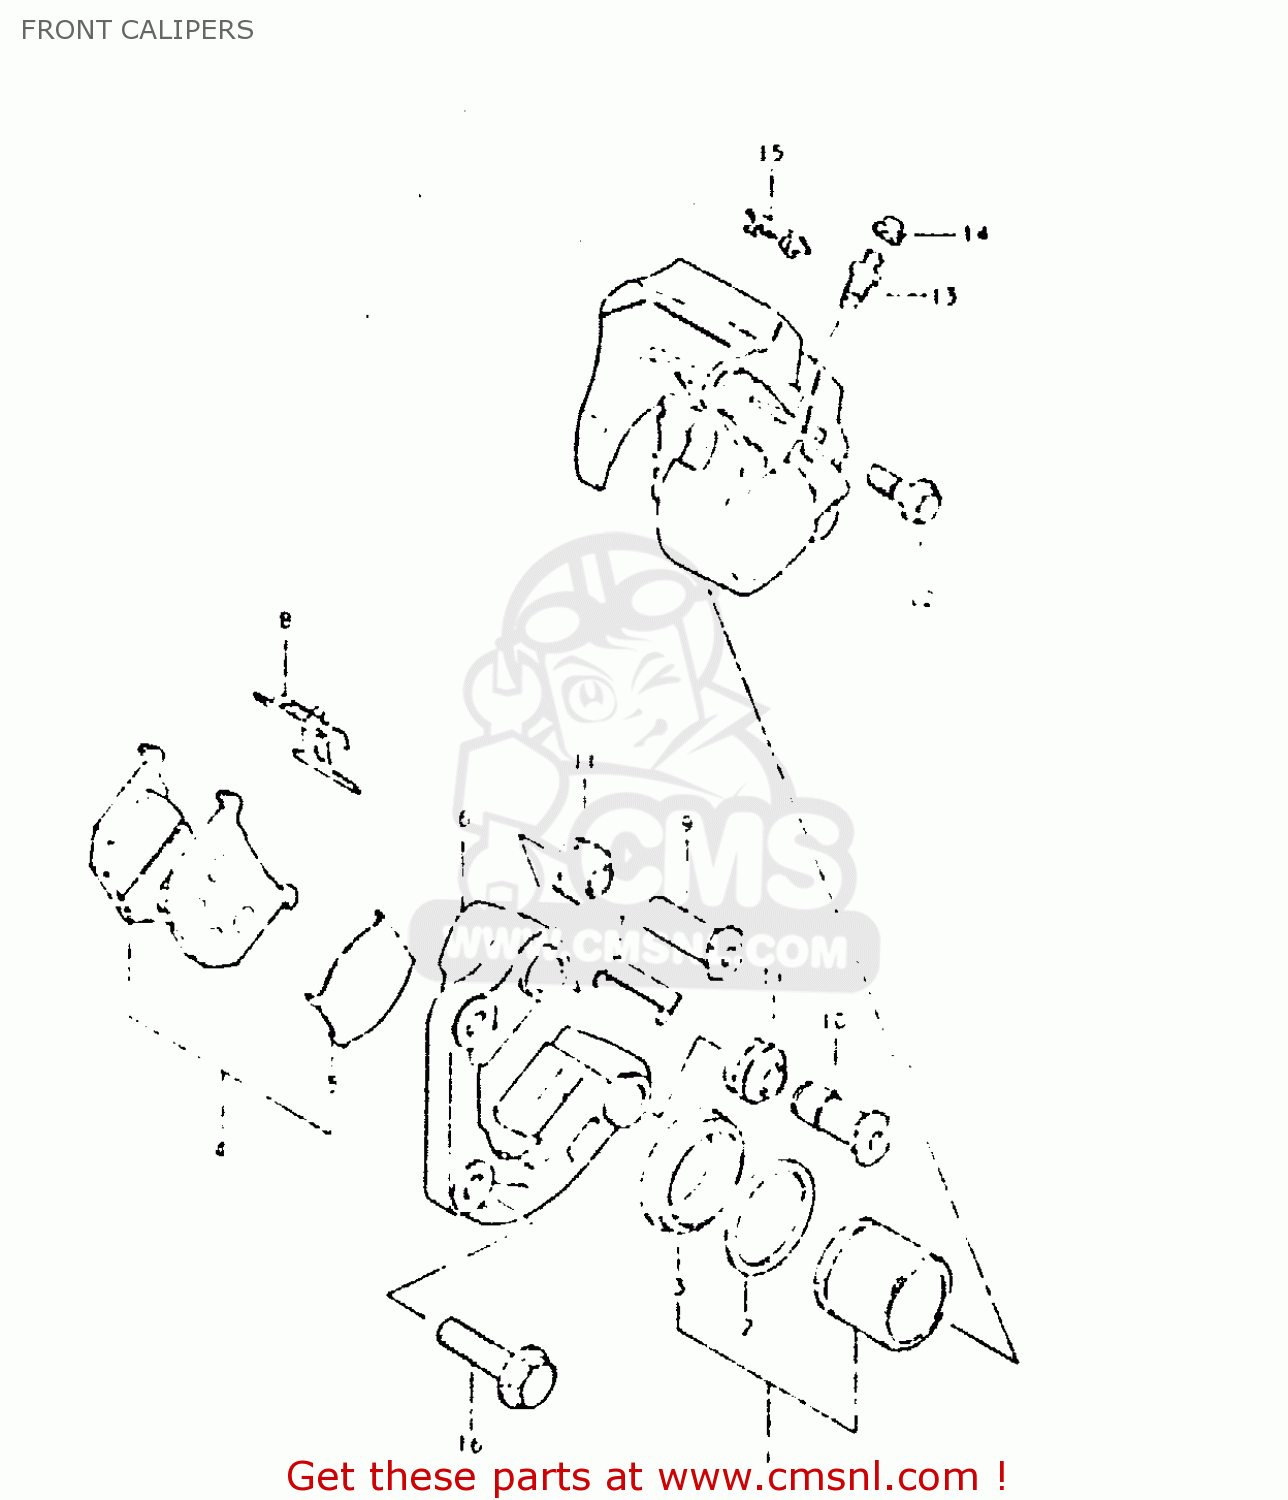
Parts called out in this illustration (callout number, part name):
1	PISTON SET
2	SEAL,FR CALIPE
3	BOOT,PISTON
4	PAD SET (MCA)
5	SHIM,PAD
6	CARRIER,CALIPER,LEFT
7	GUIDE,PAD
8	SPRING,PAD
9	AXLE NO.1
10	AXLE NO.2
11	BOOT,AXLE
12	BOLT,CALIPER HOUSING
13	BLEEDER
14	CAP,BREATHER
15	COVER,INDICATOR
16	BOLT(10X37)
